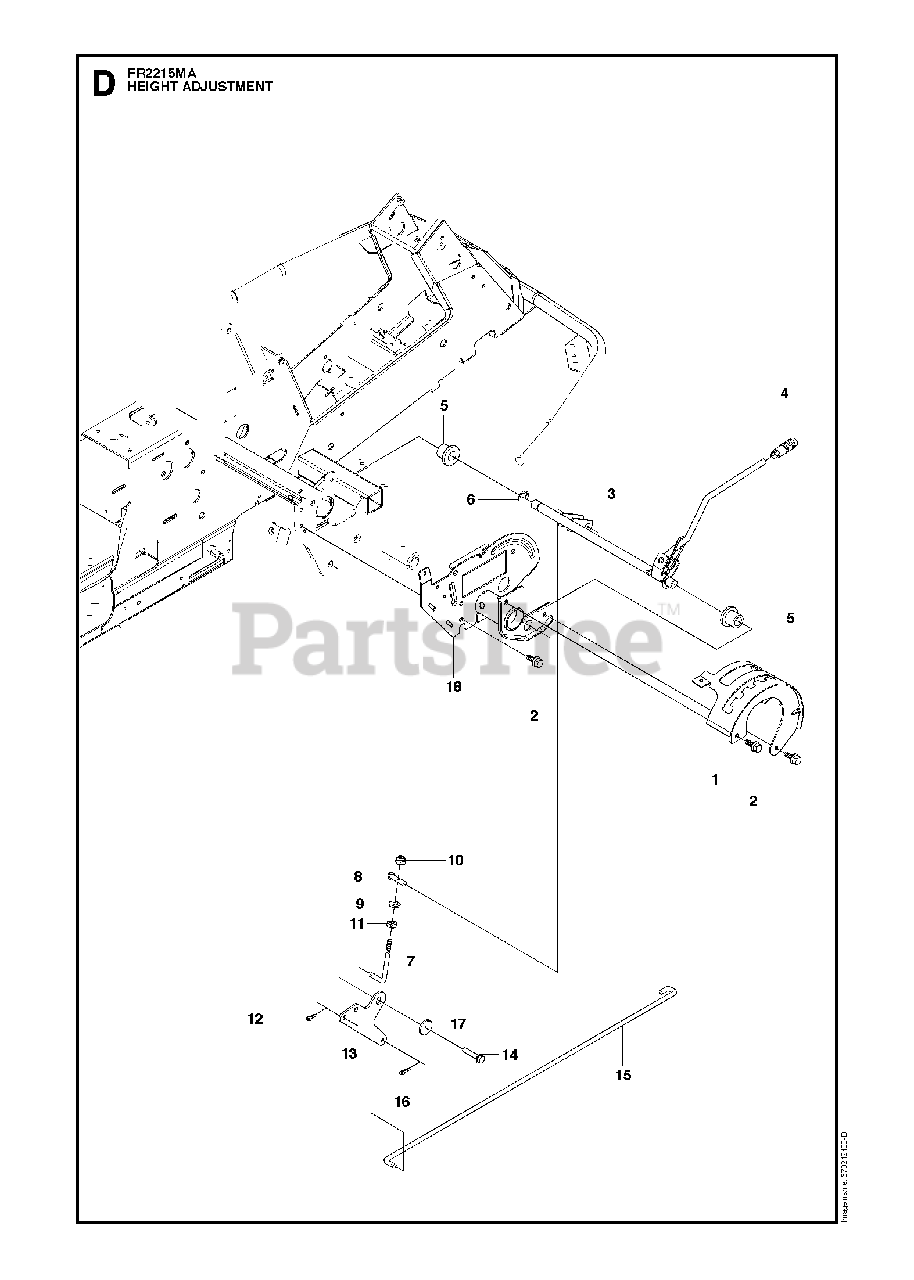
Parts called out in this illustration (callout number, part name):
4	GEAR STICK KNOB
5	BUSHING
9	WASHER
10	LOCKNUT M8
11	NUT
12	SPLIT PIN
14	BOLT
16	SPLIT PIN
17	WASHER
